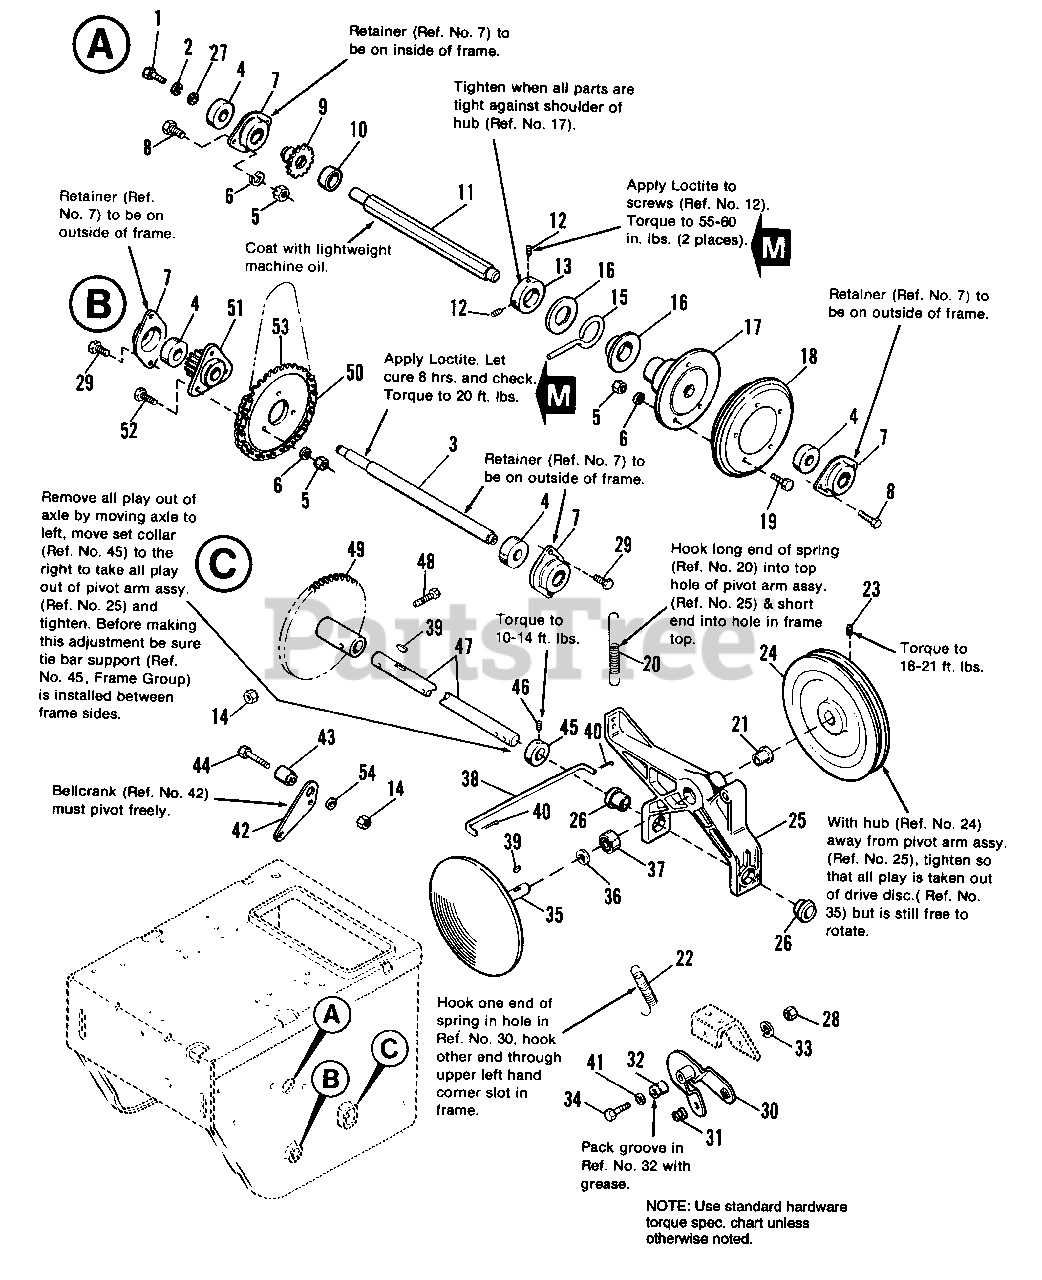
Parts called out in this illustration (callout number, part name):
1	CAPSCREW, Hex Hd., 1/4-20 x 5/8
2	LOCKWASHER, 1/4
5	NUT, Hex, 5/16-18
6	LOCKWASHER, 5/16
7	RETAINER, Bearing
8	CAPSCREW, Hex Hd., 5/16-18 x 5/8
9	SPROCKET, 10 Tooth
12	SETSCREW, Socket Hd., 1/4-20 x 3/8
14	NUT, Hex, Lock, 5/16-18
16	COLLAR, Thrust
17	HUB, Friction Disc
18	DISC, Friction
19	CAPSCREW, Hex Hd., 5/16-18 x 3/4
20	SPRING (1691774, 1691775, 1691776, 1691779)
20	SPRING (1691898, 1691899, 1691947, 1691948)
21	GEAR & BEARING ASSY., 10 Tooth (1691898, 1691899, 1691947, 1691948)
22	SPRING
23	SETSCREW, Sq. Hd., 5/16-18 x 1/2
24	PULLEY, Traction
25	ARM ASSY., Pivot w/Bushings (Incl. Ref. Nos. 21, 26 & 37)
27	WASHER, Flat, 1/4
28	NUT, Hex, 3/8-16
29	TAPTITE, 5/16-18 x 1/2
30	ARM ASSY., Shift w/Bushings (Includes Ref. No. 31)
31	BUSHING, Ball
32	BUSHING, Spacer
33	LOCKWASHER, 3/8
34	CAPSCREW, Hex Hd., 3/8-16 x 2
35	DISC, Drive
39	KEY, Woodruff, 3/16 x 5/8
40	PIN, Cotter, 1/8 x 3/4
41	WASHER, Flat, 13/32
43	BUSHING, Pivot
44	CAPSCREW, Hex Hd., 5/16-18 x 1-3/4
45	SET COLLAR
46	SETSCREW, Sq. Hd., 5/16-18 x 1/2
48	CAPSCREW, Hex Hd., 5/16-18 x 1-1/2
50	CHAIN, Drive
51	GEAR & BEARING ASSY., 10 Tooth (1691774, 1691775, 1691776, 1691779)
52	CAPSCREW, Hex Hd., 5/16-18 x 1
53	SPROCKET, 36 Tooth
54	WASHER, Flat, 11132
